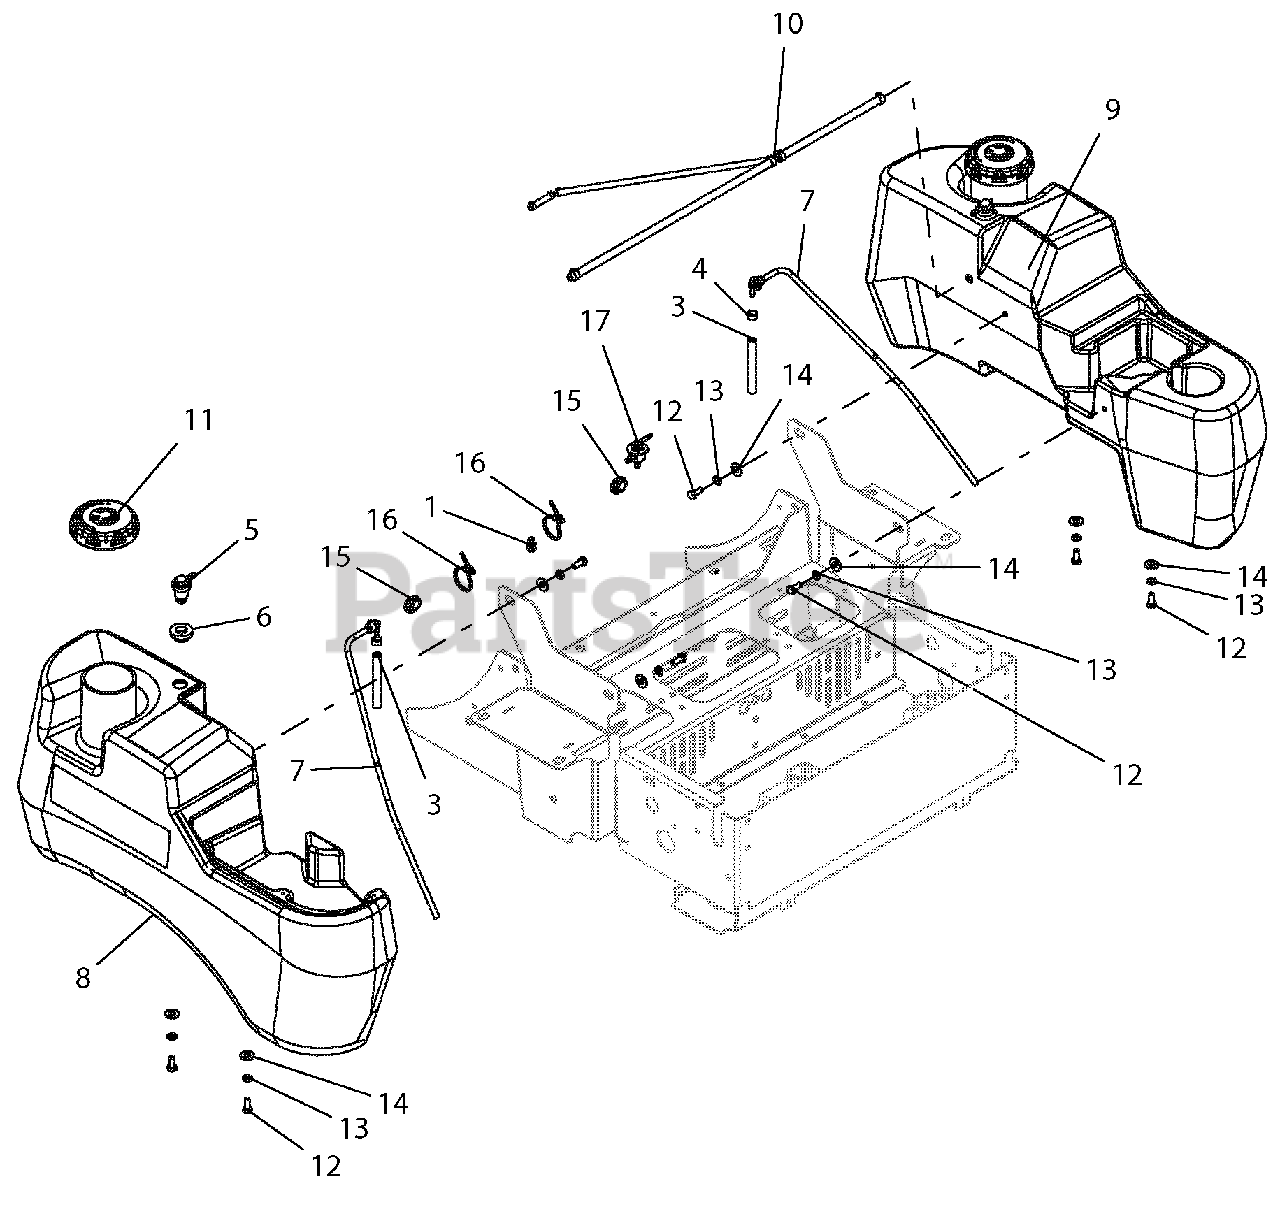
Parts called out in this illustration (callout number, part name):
1	CLIP, ROUTING (.50 ID)
3	.25 LOW-PERM GAS HOSE
4	CLAMP, FUEL LINE
5	VALVE, COMBINATION
6	GROMMET, REMOTE VENT NITRILE
7	ASM, LARGE TANK FUEL PICKUP
8	TANK, RH LARGE GRAVELY FUEL
9	TANK, LH LARGE GRAVELY FUEL
10	PT400, FUEL LINE ASSEMBLY
11	CAP, FUEL VENT-IN AUTOLOCK
12	BLT-HEX .31-18X.75 GR5 YWZC
13	WSHR-LK .31X.078 REG YWZC
14	WSHR-FL-STL.38X.875X.083 YWZC
15	GROMMET, RUBBER
16	CABLE TIE W/ TREE (.25 HOLE)
17	VALVE, FUEL
